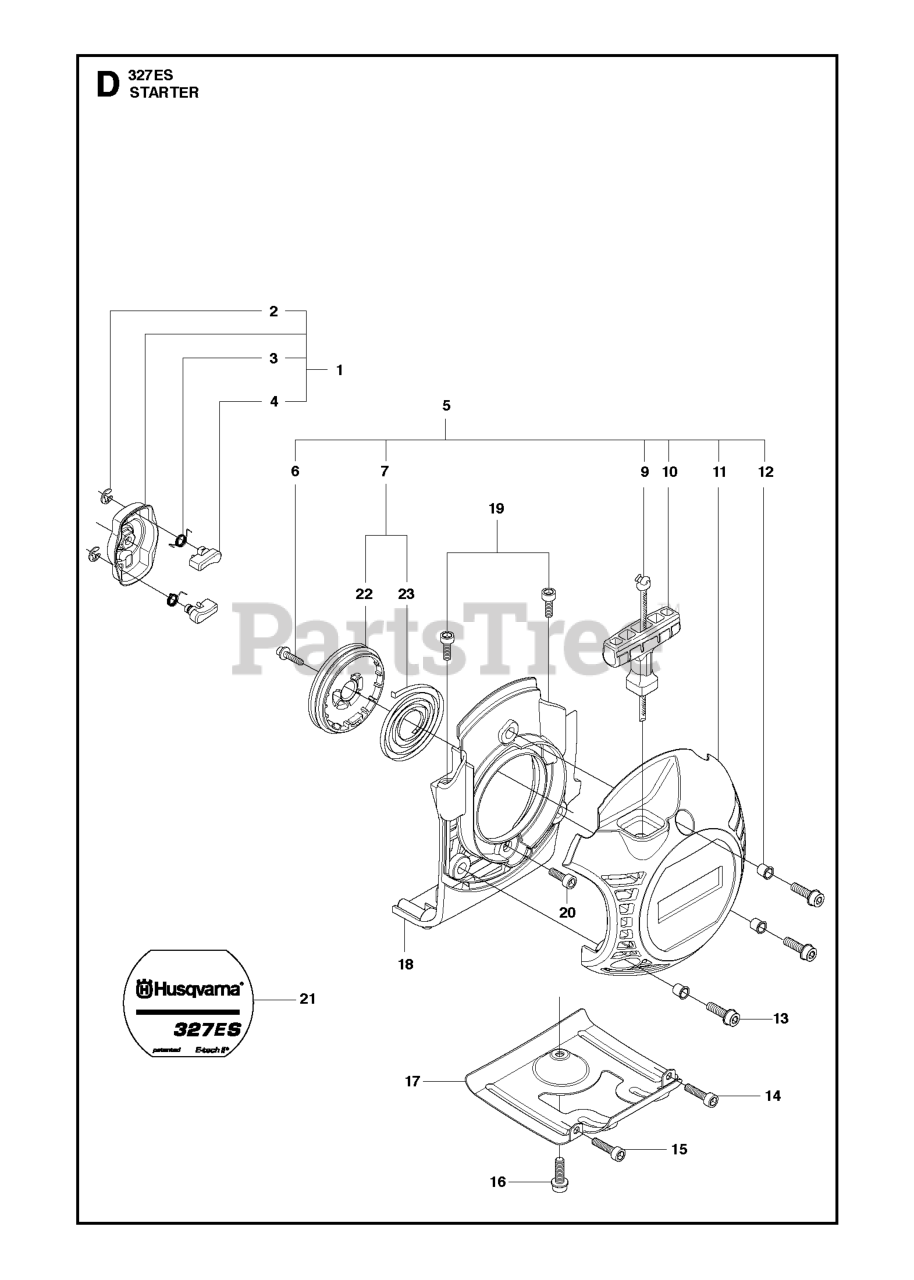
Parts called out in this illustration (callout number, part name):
1	STARTER PAWL BRIDGE
4	STARTER PAWL
5	STARTER ASSY
7	STARTER PULLEY
8	SPACING SLEEVE
9	STARTER ROPE
10	STARTER HANDLE
11	STARTER HOUSING
12	SPACING SLEEVE
13	SCREW
16	SCREW
18	BRACKET ASSY
21	DECAL STARTER HSG
22	STARTER PULLEY
23	STARTER SPRING
